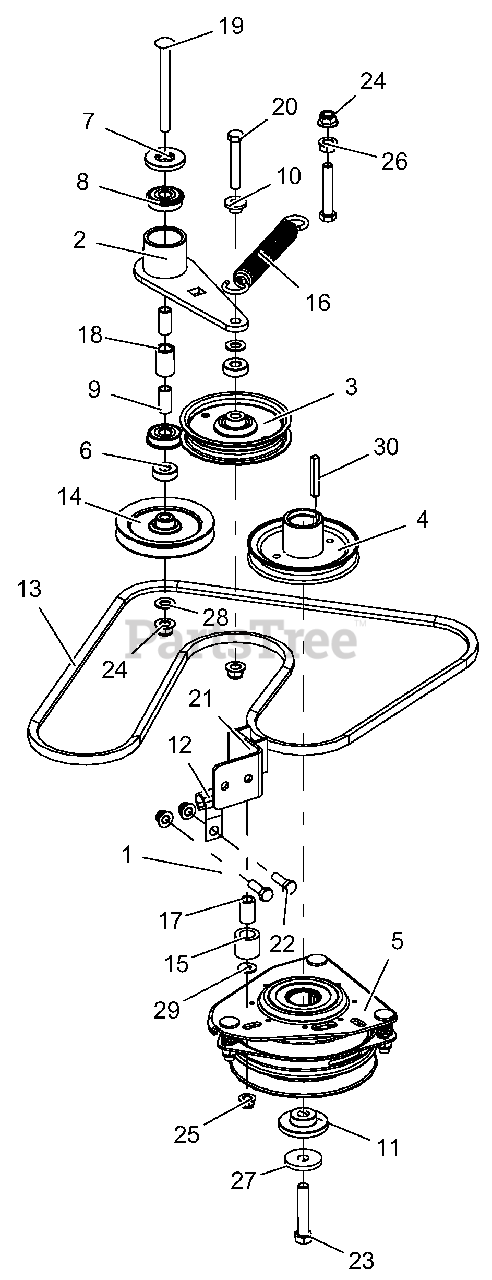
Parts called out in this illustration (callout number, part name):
1	WLDMT, CLUTCH STOP
2	WLDMT, IDLER ARM GROUND DRIVE
3	IDLER-FLAT 4.00 x .38 NWHAMSHR
4	SHEAVE, ENGINE 4.50 x 1.127 - BLACK
5	CLUTCH, ELEC OGURA GT1A-AR03
6	SPCR, .375 x 1.00 x .342
7	SPACER, IDLER ARM
8	BRG, BALL .501 x 1.38 x .438 SEALED
9	BSHG, SLV .385 x .500 x 1.045
10	BSHG, FLG .385 x .500 x .875 x .406
11	BSHG, -FLG .469 x 1.06 x .574 x 2.0
13	BELT, V- A COGGED
14	SHEAVE, IDLER -V .38 x 4.00
15	BUMPER, RUBBER .62 x 1.0 x .88 LG
16	SPRG, EXTENSION
17	BUSH., S .391 x .622 x .95 ST REV A
18	SPACER, .510 x .750 x 1.148
19	BLT-RHDSSQNK .38-16 x 4.00 G5YZ
20	BLT-HEX .38-16 x 2.25 GR5 YWZC
21	BLT-HEX .31-18 x 1.50 GR5 YWZC
22	BLT-HEX .31-18 x 1.00 GR5 YWZC
23	BLT-HEX .44-20 x 2.25 GR5 YWZC NYTORQ
24	NUT-LK-NYL-FLG .38-16 YWZC
25	NUT-LK-NYL-FLG .31-18 YWZC
26	@NUT-SPNLK-FLG .375-16 YWZC
27	WSHR, 7/16" SPRING DISC
28	WSHR-FL-STL .406 x .812 x .065 YWZ
29	WSHR-FL-STL .312 x .734 x .065 YWZ
30	KEY-STR .25 x 1.75 x .25
